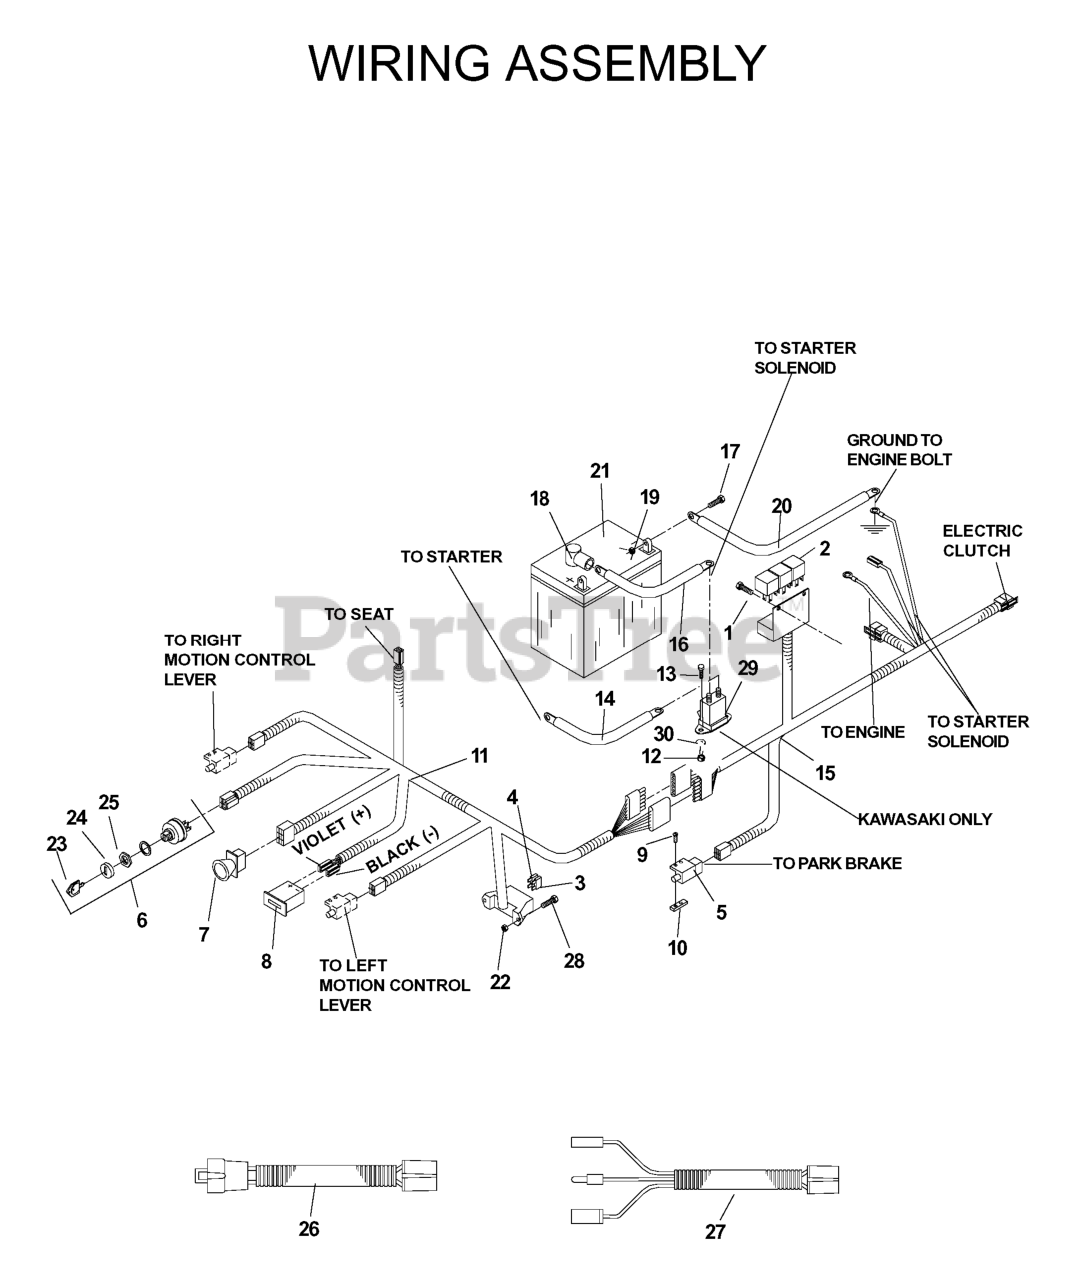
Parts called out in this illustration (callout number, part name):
1	SCREW #10 X 1/2 SELF TAPPING
3	FUSE, 7.5 AMP 32 VOLT ATO
4	FUSE, 20 AMP 32 VOLT ATO
5	SWITCH, INTERLOCK
6	IGNITION SWITCH KIT
7	RP.SWITCH, BLADE
8	DIGITAL HOUR METER
9	SCREW #10-24 X 5/8
10	TAPPED PLATE
11	CONSOLE HARNESS
12	NUT 1/4C CENTERLOCK
13	HCS 1/4C X 5/8
14	POST.CABLE LONG
15	FRAMES HARNESS
16	CABLE POSITIVE, LONG
17	HCS 5/16C X 3/4
19	NUT 5/16C CENTERLOCK
20	CABLE-NEGATIVE
21	BATTERY WET NOT SELLABLE
22	NUT 10-24 NYLOC
23	KEY-PADDED
24	CAP IGNITION NUT
25	DNO IGNITION NUT
26	KOH PIGTAIL
27	KAW PIGTAIL
28	SCREW, #1--24 X 1/2 SLOTTED
30	WASHER 1/4 INT TOOTH
